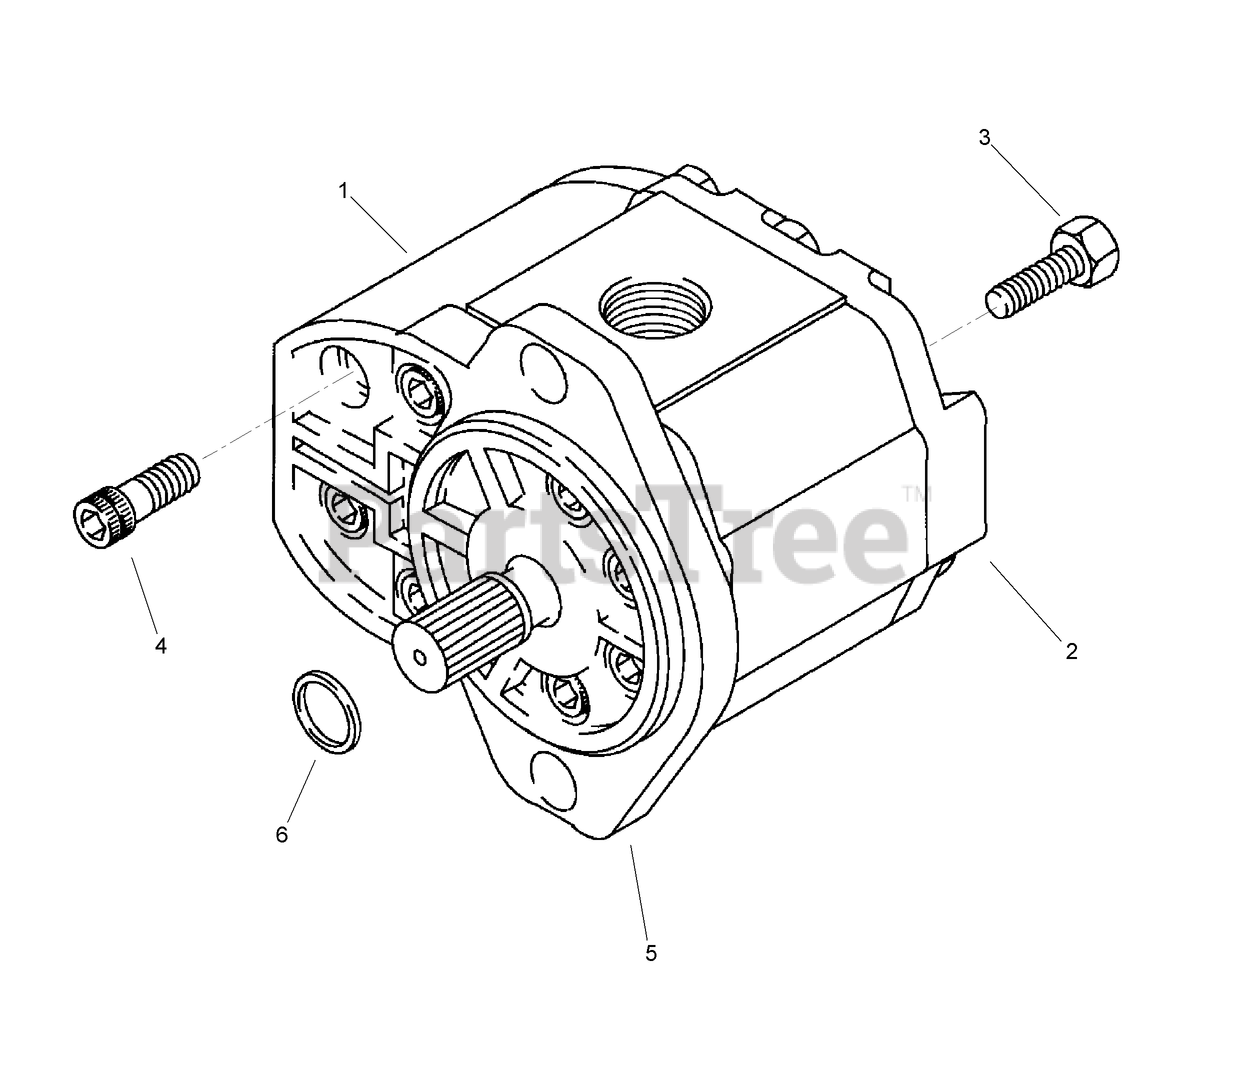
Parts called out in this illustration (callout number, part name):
1	HOUSING - Plow Motor
2	COVER - Plow Motor
4	SCREW-Soc Hd, M10 x 30 Class 8.8 ZND
5	FLANGE - Mounting, Plow Motor
6	SEAL - 25 x 42 x 6 mm, Shaft
